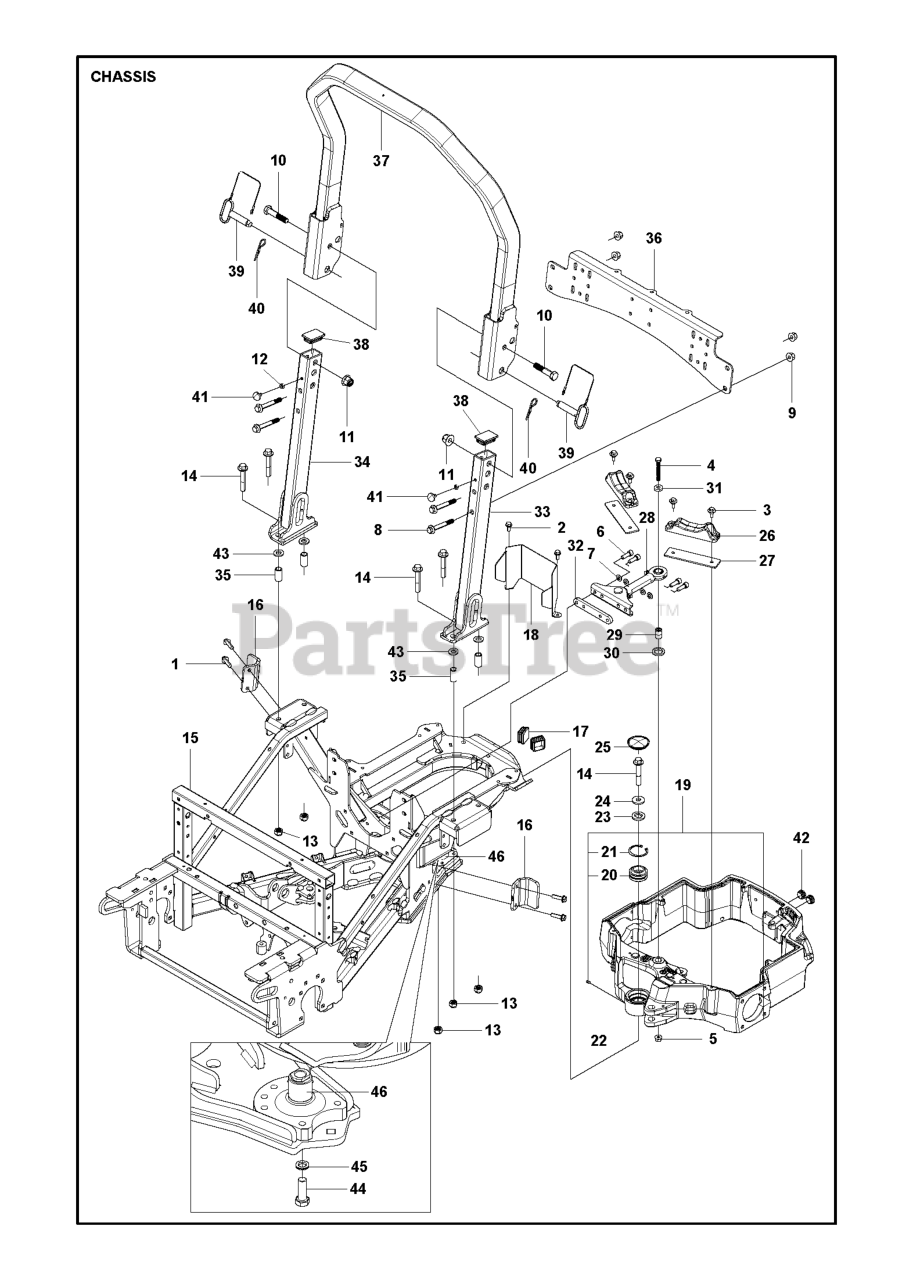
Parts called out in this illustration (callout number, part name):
3	TRIM.HUSQ.TG/CRD.SERVICE
4	RP LOGO
5	DASH.ASM.HUSQ.GT.E.RECT.W/CK
6	NUT PUSH M
14	HOOD
15	LENS.LH.TEX.GT.HUSQ.CL
18	GRILL.ASM.HUSQ.TG/CRD.W/TRIM
25	LENS.RH.TEX.GT.HUSQ.CL
34	PLATE.ENGINE.WELDED.CHASSIS
36	SCREW 5/16"
37	RP FENDER.TLT.FS.W/CPH.422
52	LOCKNUT
68	Screw 5/16-18 x 1/2 Hex, Self Tapping 5/16-18 x 1/2
130	SCREW.#10 X 0.750.BOS
137	BUMPER DASH
150	AIR.DUCT.HOOD.TEX.GT.HUSQ
152	SHIELD.BROWNING.W/TEX
161	WINDOW FUEL
162	SCREW.HI-LO.CONSOLE
165	SUPPORT.TANK.REAR.W/TEX
175	PLATE.CROSSMEMBER.HUSQ
176	SCREW.#10-24X5/8.RN.QU
177	BUSHING, STEERING
178	CARGO.ASM.NET.TXGT.W/C
180	CHASSIS
181	BUSHING.MNT.FEND.CRGO.
182	DASH.LOWER.COMMON.12V.ADAPTOR
183	BOLT.5/16-18X1-1/4 FULL.THREAD
189	SCREW
194	NUT LOCK HEX FLANGE 5/16-18
199	PLATE.DECK.LIFT.HUSQ.LT
202	VENT.SIDE.HOOD.HUSQ.RH.GREY
203	VENT.SIDE.HOOD.HUSQ.LH.GRAY
204	HOOD VENT
205	SKIRT.HOOD.SIDE.HUSQ.RH.GREY
206	SKIRT.HOOD.SIDE.HUSQ.LH.GREY
207	BEZEL.RH.TEX.GT.HUSQ
208	BEZEL.LH.TEX.GT.HUSQ
209	INSERT.HEX.GRILL.HUSQ.GREY
210	INSERT.HEX.GRILL.HUSQ.
211	INSERT.HEX.GRILL.HUSQ.
212	INSERT.HEX.GRILL.HUSQ.
213	BOLT
214	CLIP.RETAINER.TINNER.
217	ROD.PIVOT.HOOD
218	X-PIECE.HOOD.STOP.NON/
228	STUD.FASTNER.W/ANTI-ROTATE
233	BOLT.SHOULDER
234	BUMPER.HOOD.TEX.HUSQVARNA
235	SPACER FENDER
236	NUT.CENTERLOCK.5/16-
282	CLIP.RETAINER.CONSOLE.LT.HUSQ
283	CONSOLE.DECK.LFT.R.SDFL.HUSQLT
284	CONSOLE.CNTRL.
285	CONSOLE INSERT RH
286	CONSOLE.INSRT.LH.HUSQ.LT.BLACK
287	SCREW 1/4X20
